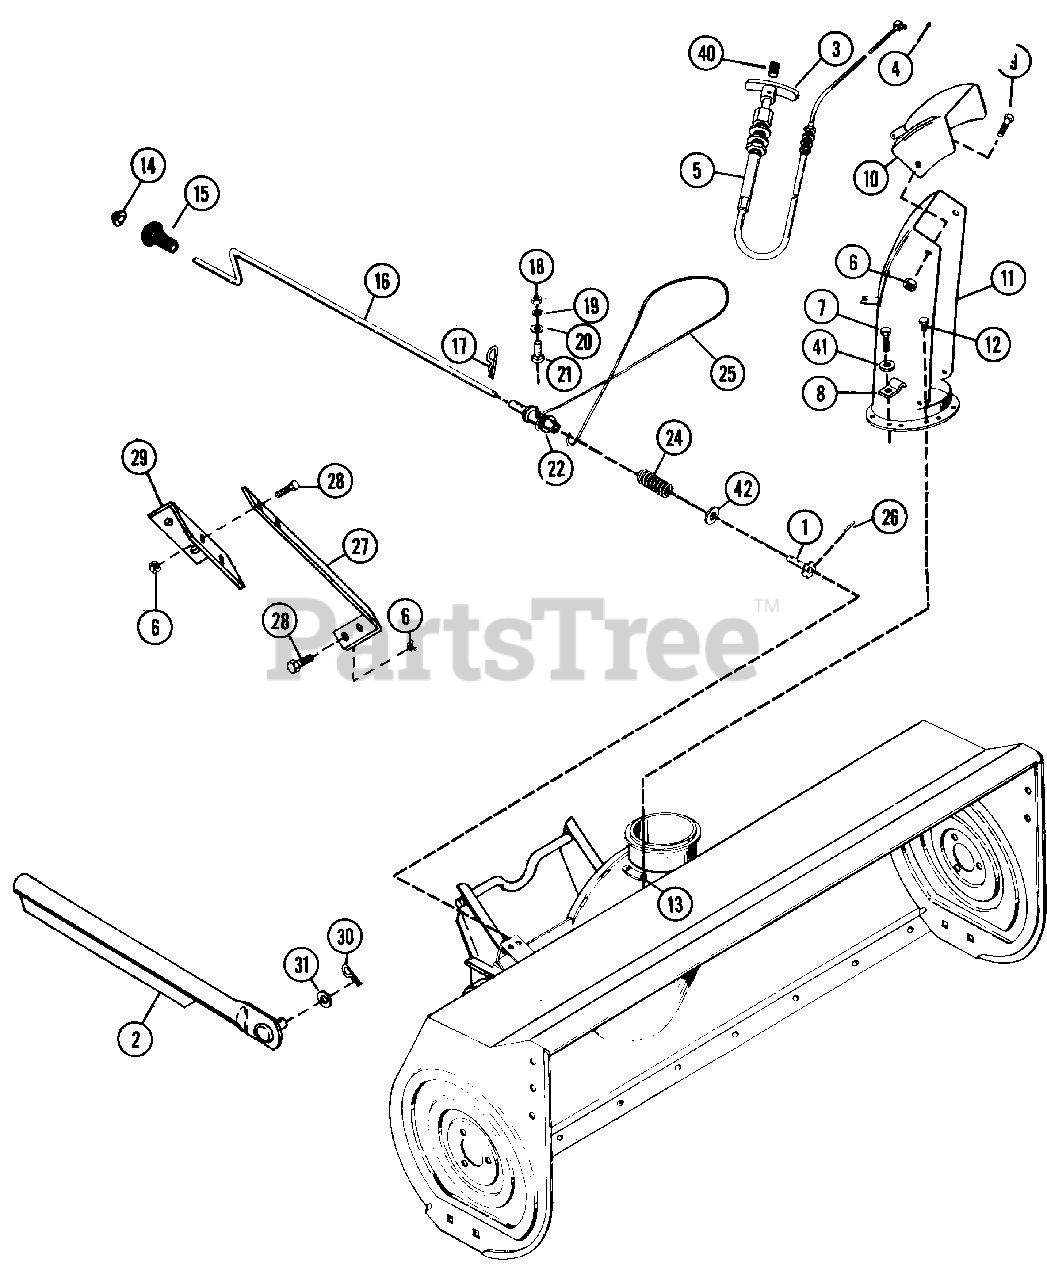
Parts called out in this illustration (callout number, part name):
1	ARM, DISC
2	WELDMENT, PUSH ROD
3	HANDLE, TEE
4	PIN, COTTER .09X.75
5	CABLE, CONTROL
6	NUT, LOCK 3/8-16
7	SCREW, TAPTITE 10-24.75
8	CLAMP, CABLE
9	BOLT, HEX 3/8-16X.75
10	DEFLECTOR, CHUTE
11	CHUTE, DISCHARGE
12	SCREW, TAPTITE 10-24X.375
13	CLAMP, CHUTE
14	CAP
15	KNOB
16	CRANK, CHUTE CONTROL
17	HAIR PIN, INTERNAL
18	NUT, HEX 1/4-20
19	WASHER, LOCK 5/16 REG.
20	WASHER, FLAT .281X.625X.065
21	BOLT, 1/4-20X.625 RD HD SQ NK
22	SPOOL
24	SPRING, COMPRESSION
25	CABLE
26	PIN, SPRING .187X1.000
27	BAR, CRANK BRACKET
28	BOLT, HEX 3/8-16X1.00
29	BRACKET, CRANK SUPPORT
30	COTTER, HAIR PIN
31	WASHER, FLAT .812X1.469X.134
40	SCREW, MACHINE 10-32X.50
41	WASHER, FLAT .219X.438X.049
42	WASHER, .62X1.005X.06
NS	DECAL, GRAVELY LOGO
NS	DECAL, DANGER FOOT
NS	DECAL, DANGER HAND
